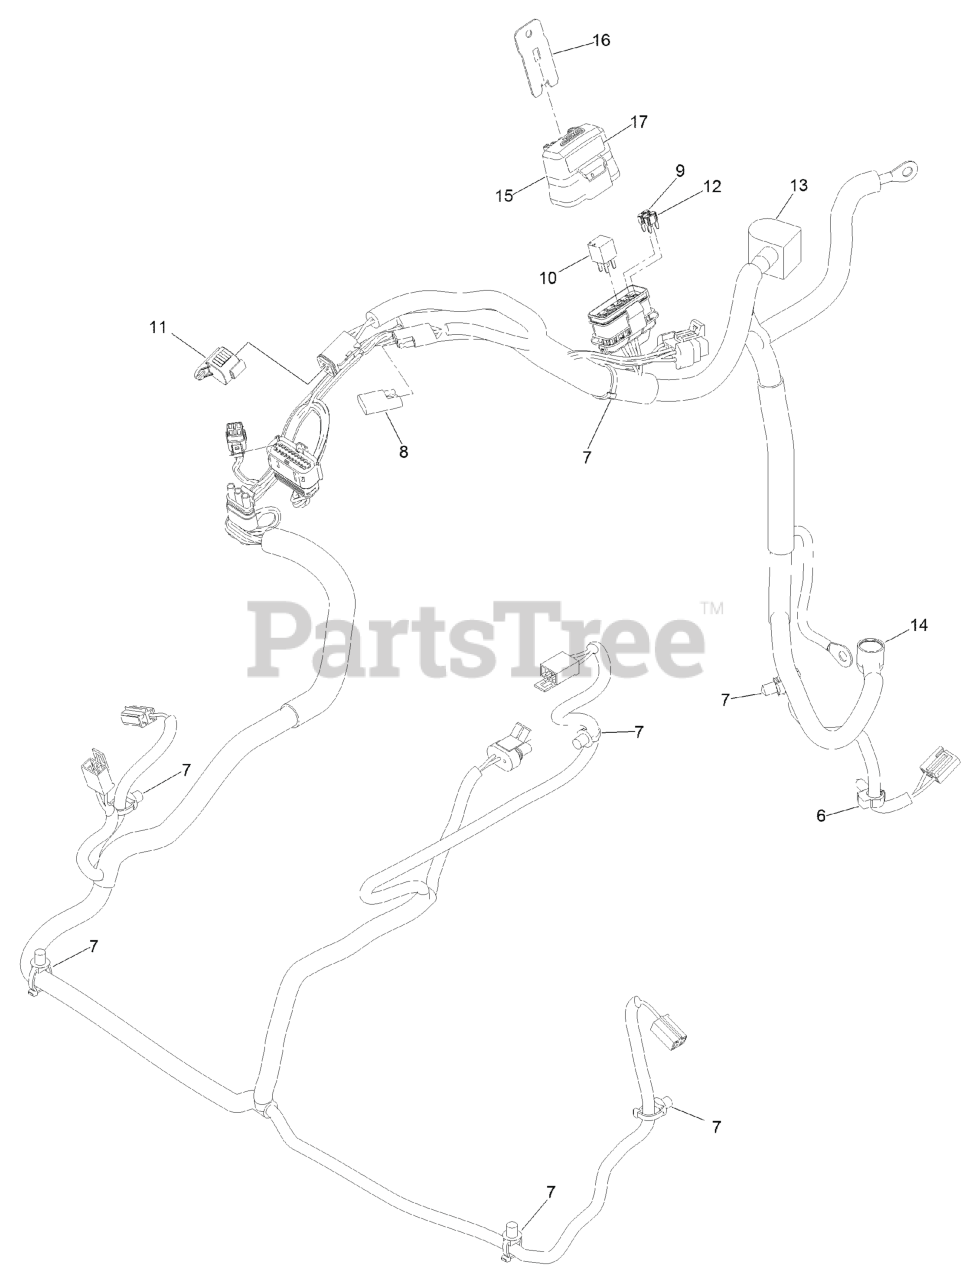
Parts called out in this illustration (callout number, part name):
6	CLIP-HARNESS
7	CLIP-TIE
8	Cap-Plug
9	FUSE-MINI BLADE, 20 AMP
10	RELAY-MICRO
11	CAP-PLUG, 6 WAY
12	FUSE-MINI BLADE, 15 AMP
13	INSULATOR-BATTERY
14	INSULATOR-SOLENOID
15	COVER-BLOCK, FUSE
16	CLIP-MOUNTING
17	DECAL-FUSE
